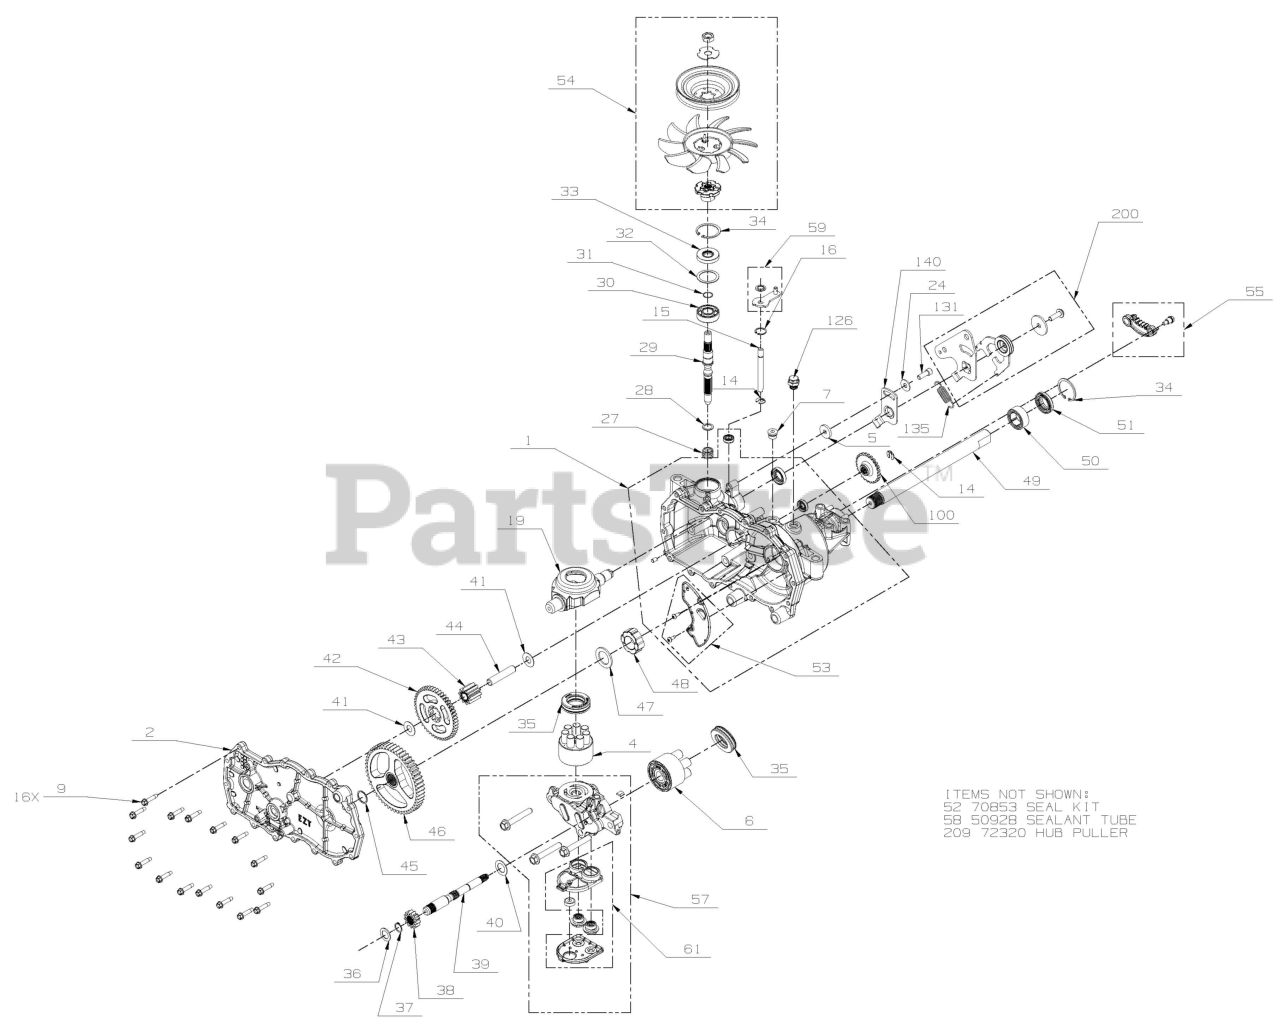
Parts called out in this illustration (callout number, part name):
1	ASSEMBLY, MAIN HOUSING
2	ASSEMBLY, SIDE HOUSING
4	ASSY, BLOCK 7 PISTON
6	KIT, 10 CC BLOCK
7	PLUG, 9/16-18 STR THREAD SOCKET HEAD
9	SCREW,HEX WASHER 1/4-20X1.125
14	RING. RETAINING
15	ROD, BYPASS
16	RING, RET .750
19	TRUNNION, SWASHPLATE
27	SPRING. BLOCK
28	WASHER. THRUST .59 X .79 X .04
29	SHAFT, INPUT
30	BRG, BALL 17X40X12
31	RING, RET WIRE .561 ID
32	WASHER 1.23X1.56X.04
33	SEAL, LIP 17X40X7
34	RING, RET 1.56 INT
35	BEARING. THRUST 30 X 52 X 13
36	WASHER .63X1.0X.05
37	RING, RET 62 EXT
38	GEAR, 13T PINNION
39	SHAFT, MOTOR
40	WASHER .71 X 1.16 X .04
41	WASHER .5X1.0X.032
42	GEAR, 10T/48T
43	GEAR, 10T JACKSHAFT
44	JACK SHAFT (PIN)
47	WASHER, 1.018 X 1.571 X .105 FLAT
48	BUSHING, SLEEVE (INBOARD)
49	SHAFT, AXLE 1.00 X 11.70 DD
52	KIT, SEALS AND RETAINING
53	KIT, EXPANSION PLATE RH
54	FAN PULLEY KIT 4.5X1.625
55	BRAKE ARM-LH, EZT
57	KIT, CENTER SECTION, W/FILTER - RH
58	SEALANT TUBE 10.1OZ.
59	KIT, BYPASS ARM
61	KIT, FILTER
100	DISC, COG BRAKE
126	ASSEMBLY, FITTING 9/16-18 BREATHER
131	KIT, RTN SCREWS
135	SPRING, HYDROGEAR P/N 51833
140	ARM, NEUTRAL RIGHT
200	KIT, RTN BIDIRECTIONAL
